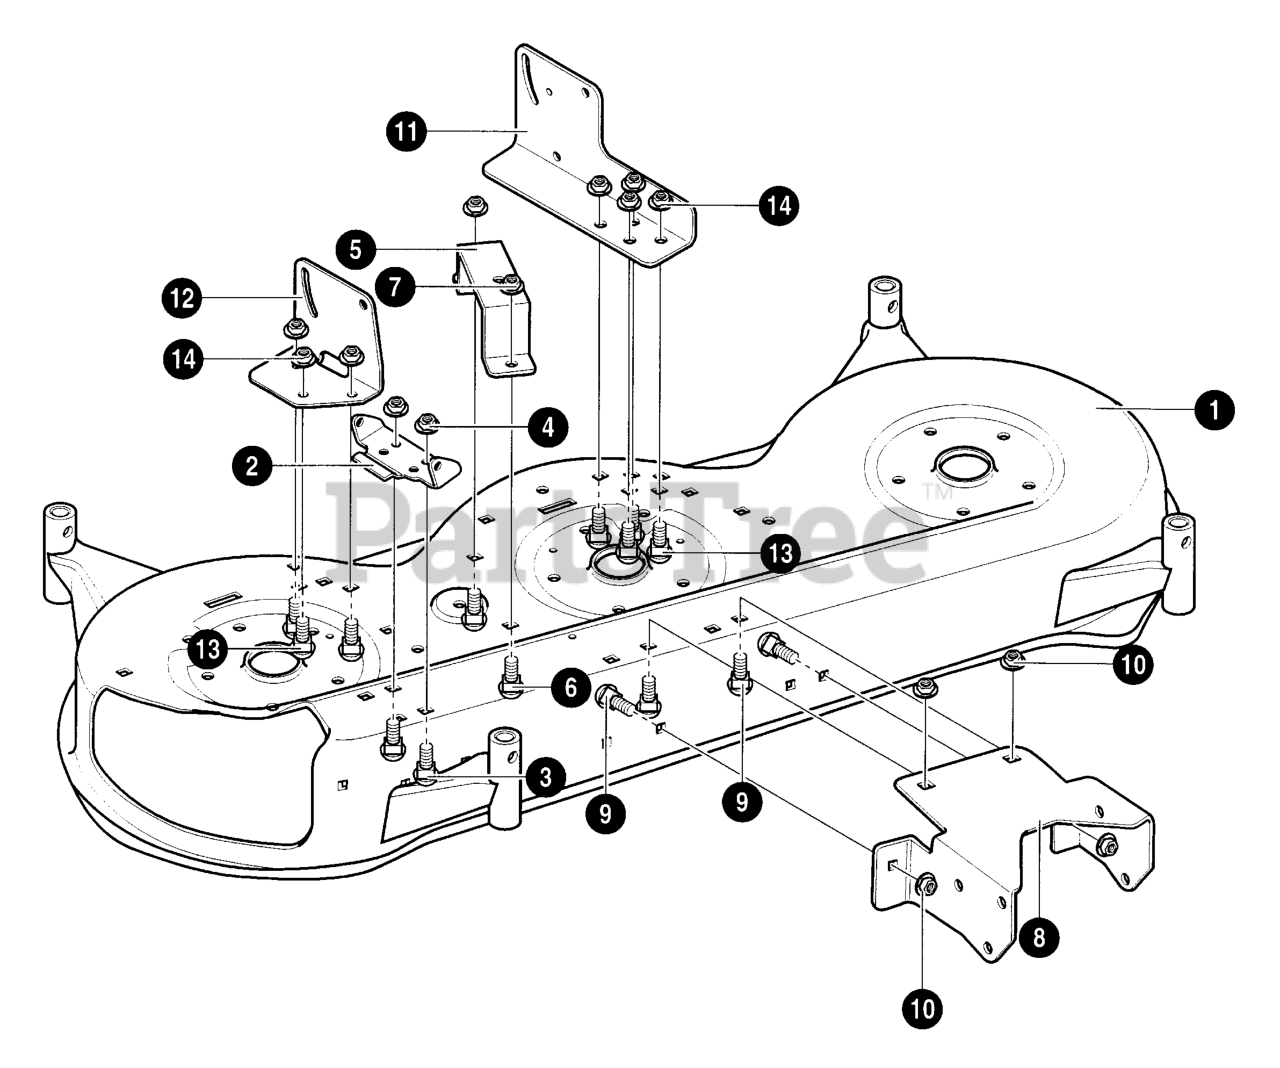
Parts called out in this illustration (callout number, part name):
1	ASSY BLD HSING 42"
2	HINGE, CHUTE BRACKET
3	BOLT, 5/16- 18X.63
4	NUT, 5/16- 18
5	BRACKET, BELL CRANK
6	BOLT, 5/16- 18X.63
7	NUT, 5/16- 18
8	BRACKET, FRONT DECK
9	BOLT, 5/16- 18X.63
10	NUT, 5/16- 18
11	BRACKET, LEFT LIFTER
12	BRACKET, RIGHT LIFTER
13	BOLT, 5/16- 18X.63
14	NUT, 5/16- 18
